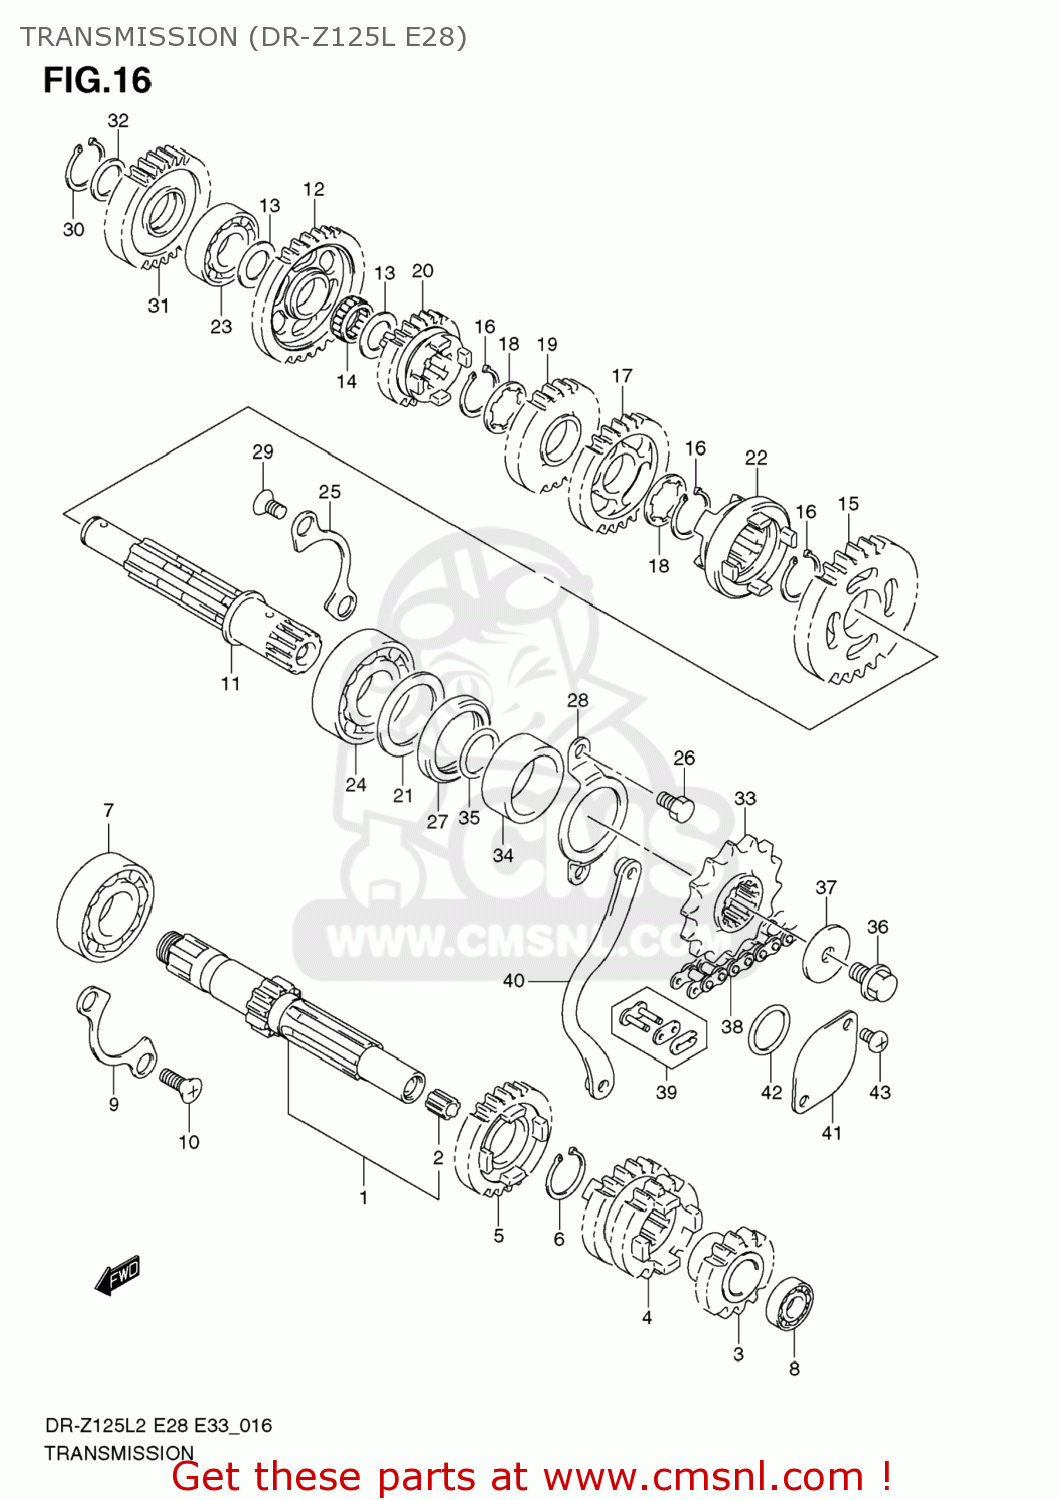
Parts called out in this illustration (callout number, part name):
1	SHAFT,COUNTER(NT:11)
2	BUSH
3	GEAR,2ND DRIVE(NT:14)
4	GEAR,3RD & 4TH DRIVEN(NT:19/21
5	GEAR,5TH DRIVE(NT:26)
6	CIRCLIP
7	BEARING(20X47X14)
8	BEARING
9	RETAINER,DRIVE SHAFT BEARING
10	SCREW(6X12)
11	SHAFT,DRIVE
12	GEAR,1ST DRIVEN(NT:33)
13	WASHER
14	BEARING(15X19X7.8)
15	GEAR,2ND DRIVEN(NT:26)
16	CIRCLIP
17	GEAR,3RD DRIVEN(NT:26)
18	WASHER,LOCK
19	GEAR,4TH DRIVEN(NT:23)
20	GEAR,5TH DRIVEN(NT:24)
21	WASHER,OIL SEALING
22	WHEEL,SLIDING DOG
23	BEARING(15X36X12)
24	BEARING(22X50X14)
25	RETAINER,DRIVE SHAFT BEARING
26	BOLT
27	SEAL,OIL(30X40X6)
28	RETAINER,DRIVE SHAFT OIL SEAL
29	SCREW(6X12)
30	CIRCLIP
31	GEAR,KICK STARTER IDLE(NT:26)
32	SHIM(15X20X1)
33	SPROCKET,ENGINE(14T)
34	SPACER,ENGINE SPROCKET
35	O RING(D:2.5,ID:21)
36	BOLT
37	WASHER
38	CHAIN,DRIVE
39	JOINT SET,CHAIN
40	PLATE,FR CHAIN GUIDE
41	CAP,NEUTRAL SWITCH HOLE
42	O RING(D:2.4,ID:21.8)
43	SCREW
